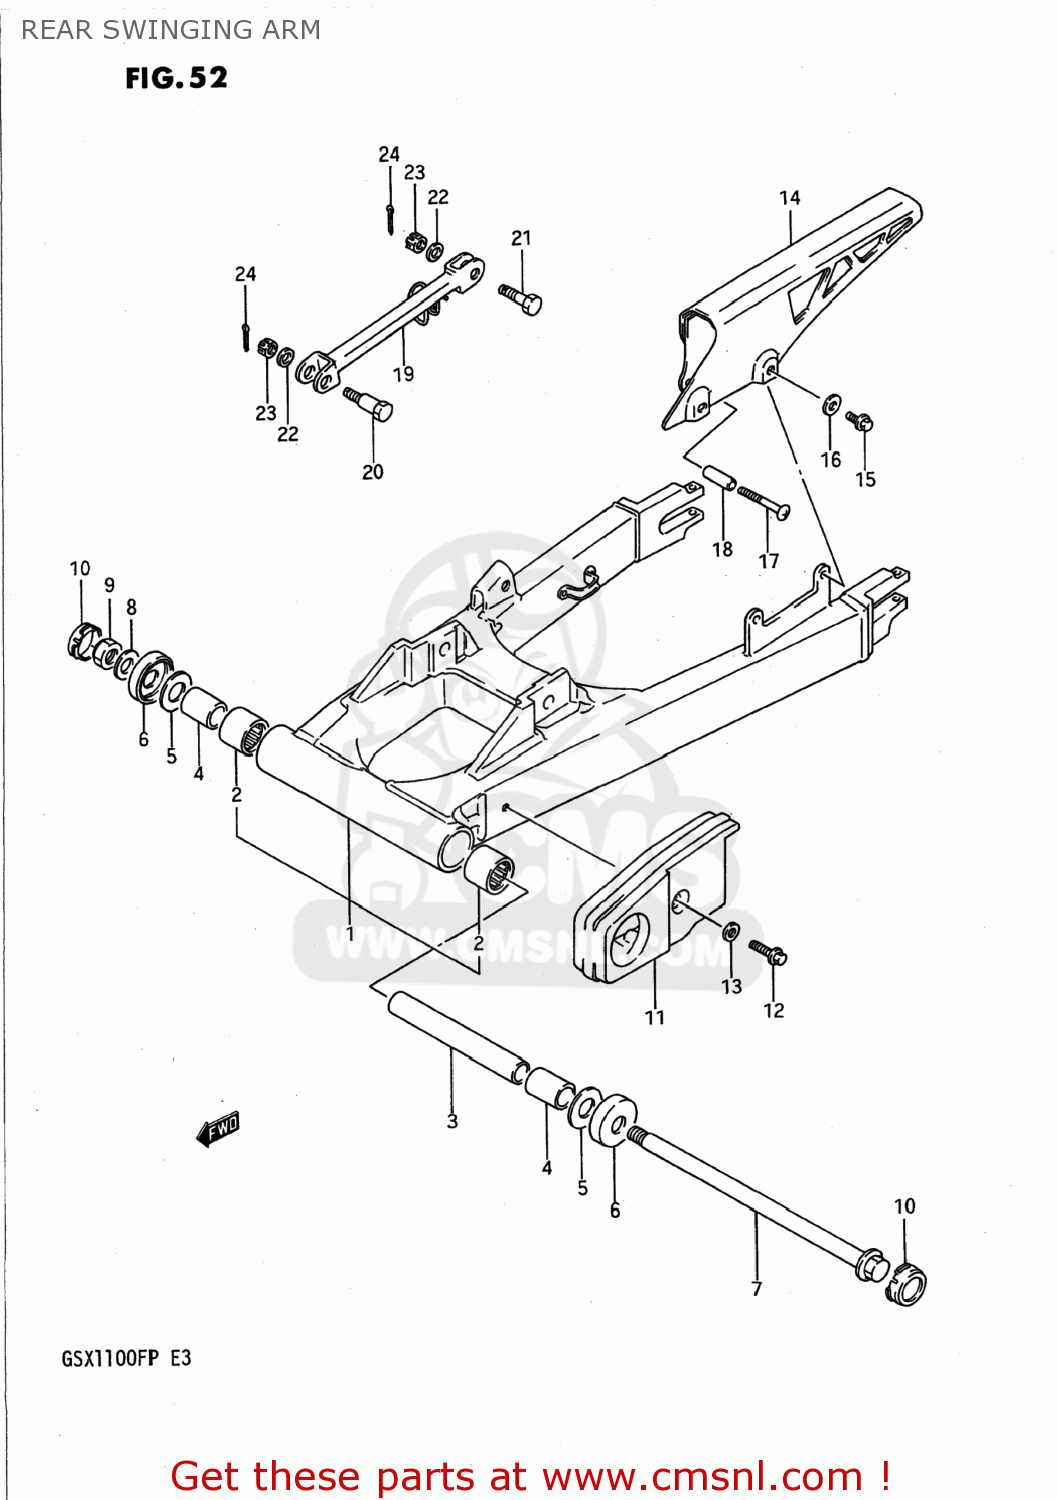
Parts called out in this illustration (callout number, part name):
1	SWING ARM ASSEMBLY,REAR
2	BEARING(25X33X30)
3	SPACER,REAR SWING ARM PIVOT
4	SPACER,RR SWGARM PIVOT
5	WASHER
6	COVER,RR SWINGINGARM PIVOT
7	SHAFT,REAR SWING ARM PIVOT
8	WASHER(14X27X3)
9	NUT
10	CAP,RR SWINGING ARM PIVOT
11	BUFFER,CHAIN TOUCH DEFENSE
12	BOLT 6X20
13	WASHER
14	CASE,CHAIN
15	BOLT 6X12
16	WASHER
17	SCREW
18	SPACER(6.5X10.5X40)
19	TORQUELINK,RR
20	BOLT
21	BOLT
22	WASHER 10MM
23	NUT
24	PIN 20X20
